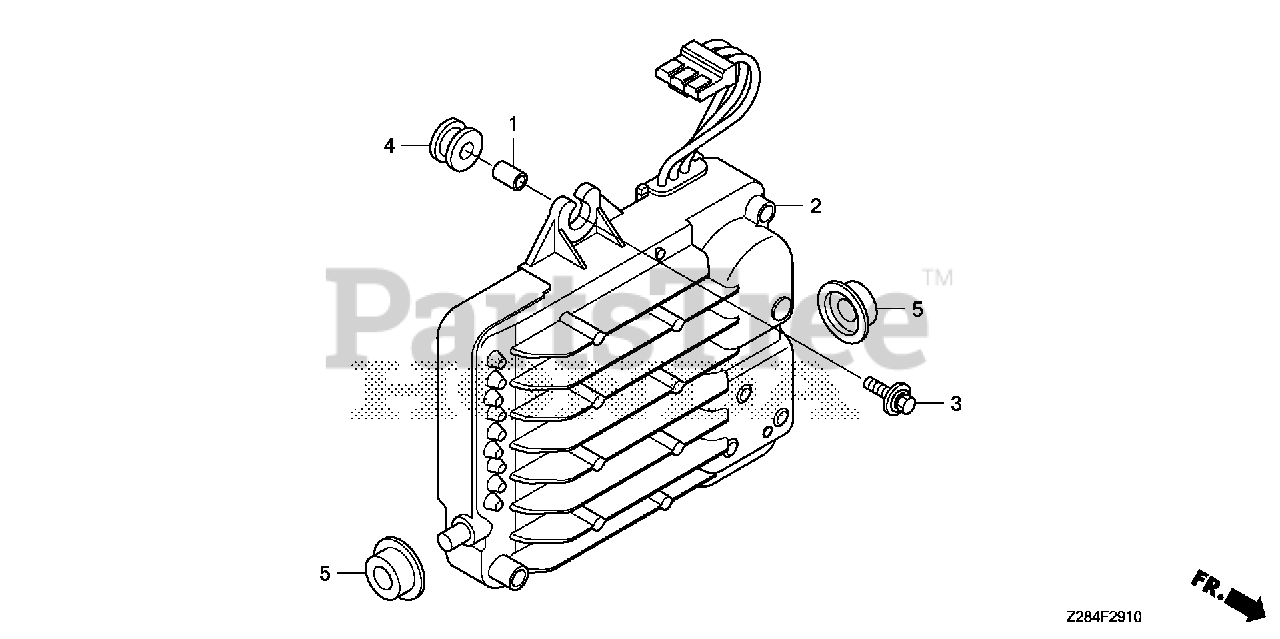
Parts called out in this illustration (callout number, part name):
1	COLLAR, IN. JOINT
2	INVERTER UNIT
3	BOLT-WASHER (6X25)
4	RUBBER, INVERTER UNIT
5	RUBBER, INVERTER MOUNT
